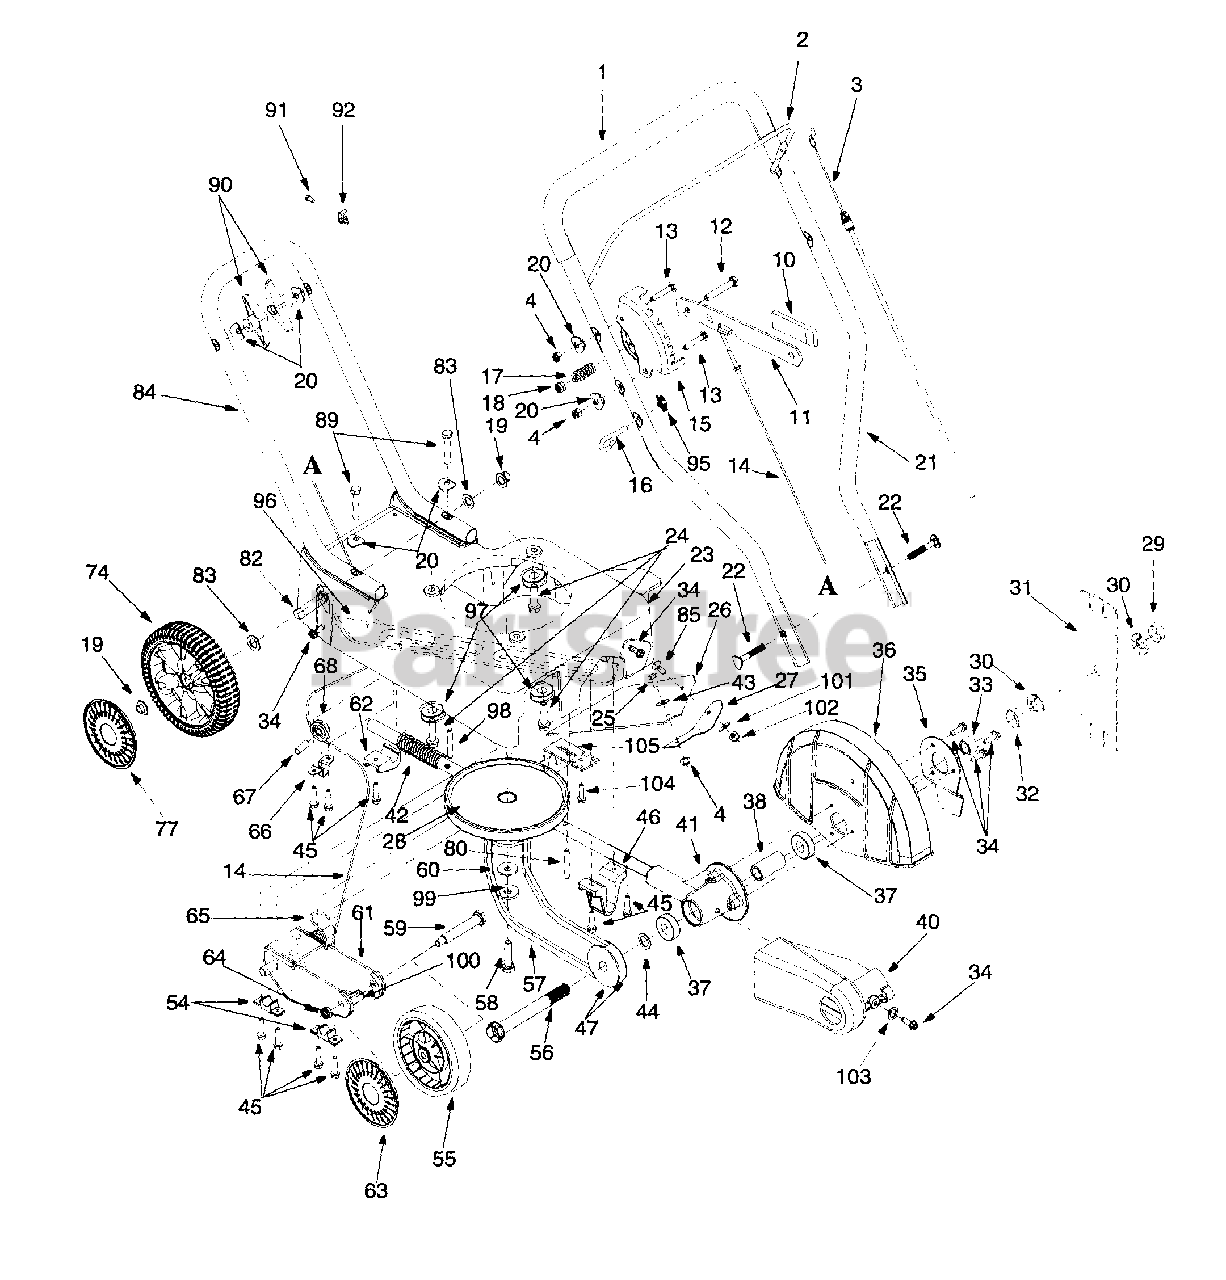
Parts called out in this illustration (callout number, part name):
1	Foam Grip
3	Control Cable 34" B & S
4	Hex Lock Nut 1/4-20
10	Depth Lever Grip
12	Hex Screw 5/16-18 x 2.0 Lg.
13	Thrust Screw 1/4-20 x 1.5
14	Depth Cable
15	Depth Bracket
16	Eye Bolt 1/4-20
17	Compression Spring .550 O.D. x 1.3
18	Hex Lock Nut 5/16-18
19	Push Cap
20	Washer .320 ID x .93 O.D.
23	Edger Base Ass'y
24	Tapp Screw w/Hex Lock Wash 3/8-16
25	Hex Screw 1/4-20 x .50 Lg.
26	Discharge Shield Deflector
27	Deflector Keeper
28	Engine Pulley
29	Hex Jam Nut 5/8-18
30	Bell Washer .63 I.D. x 1.25 O.D. x .18
32	Hex Jam Nut 5/8-18
33	Spacer .628 x .875 x .545 Lg.
34	Hx Scr. w/Wash.: TT: 1/4-20 x .750 Lg.
37	Ball Bearing .62 I.D. x 1.38 O.D. x .4
38	Spacer .628 x .875 x 1.818 Lg.
40	Belt Guard
41	Spindle w/Insert
42	Compression Spring: Arbor
43	Flat Washer .283 I.D x .75 O.D. x .030
44	Flat Washer .635 I.D. x .93 O.D. x .06
45	Hex Screw w/Wash 1/4
46	Front Rod Handler
47	Pulley
54	Black Bushing .515 Dia. x .62
55	Wheel 7 x 1.5 Star Diamond White
56	Hex Bolt 5/8-18 x 5.25 Lg.
57	V-Belt
58	Hex Screw; 3/8-24 x 1.50 Lg.
59	Shoulder Screw .500 x 2.62: 3/8-16
60	Flat Washer .38 OD x 1.38 OD
61	Front Wheel Brkt Ass'y.
62	Rear Rod Handler
63	Hubcap: Spoke w/Hole Gray
64	Jam Lock Nut 3/8-16
65	Torsion Spring
68	Cable Roller Pulley
74	Wheel: 8 x 1.7 Star Diamond White
77	Hubcap: Radial Spoke Gray
80	Pin 1/4 x 2.0" Lg.
83	Flat Wash. .531 I.D. x .675 O.D. x .06
89	Hex Screw 5/16-18 x 1.75 Lg.
90	Wing Knob Nut 5/16-18
91	Hex Scr. w/Wash.: T: #10-32 x .625 Lg.
92	Clamp B&S Throttle
95	Handle Knob
98	Roll Pin
99	Bell Washer .396 ID x 1.14 OD
100	Spacer .520 ID x .660 Lg.
101	Lock Washer 1/4
102	Hex Nut 1/4-20
103	Flat Washer 9/32 x 1/2
104	Hex Washer Screw 1/4-15 x 1.0
105	Stabilizer Bracket
